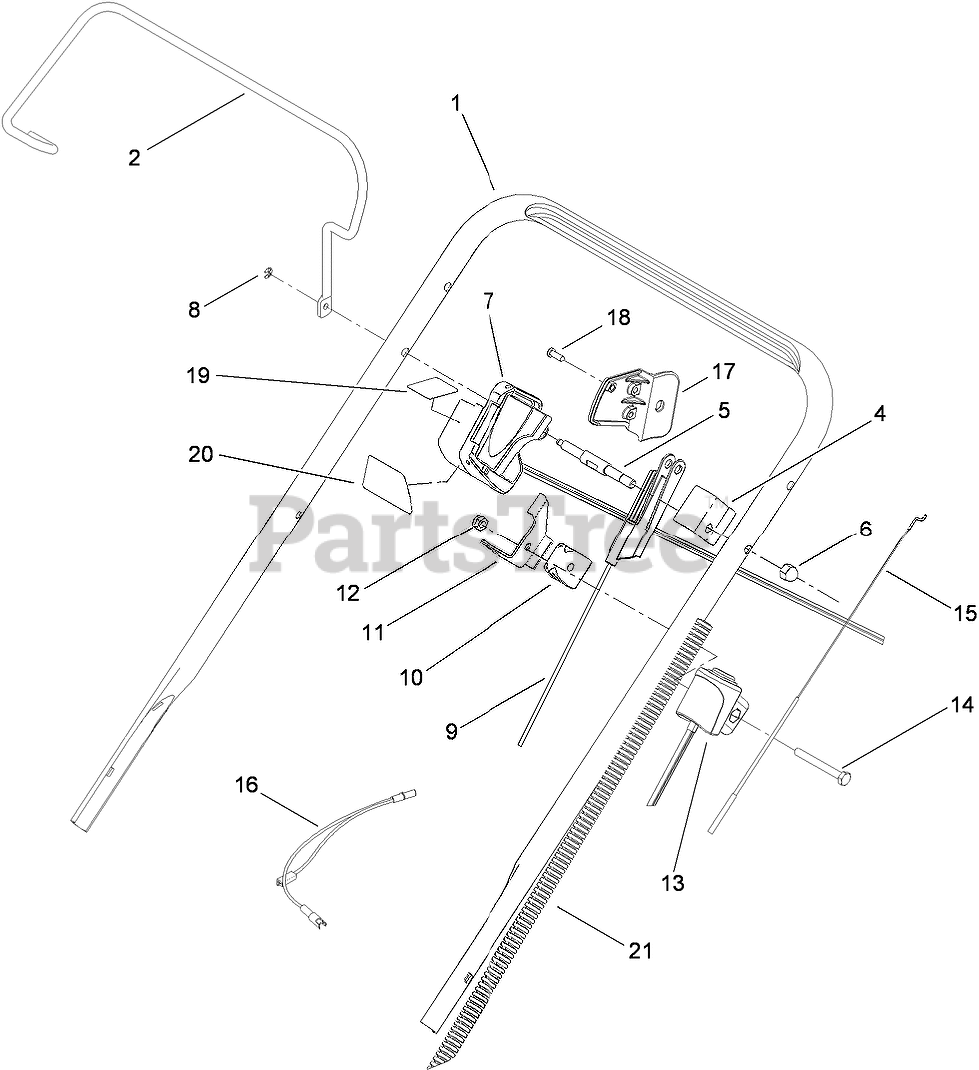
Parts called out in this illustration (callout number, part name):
1	HANDLE-UPPER
2	BAIL-BRAKE
4	BRACKET-HANDLE, STOP
5	PIN-PIVOT
6	NUT-LOCK, CAP
7	SAFTEY SWITCH ASM
8	RING-RETAINING
9	CABLE-BRAKE
10	ANCHOR-CABLE, UPPER
11	BRACKET-STOP
12	NUT-LOCK, NI
13	SWITCH HOUSING ASM
14	SCREW-HH
15	CABLE-TRACTION
16	HARNESS-WIRE
17	COVER-SWITCH
18	SCREW-PPH
19	DECAL-CONTROL, BLADE
20	DECAL-BRAKE CONTROL, BLADE
21	TUBE-LOOM, SPLIT
